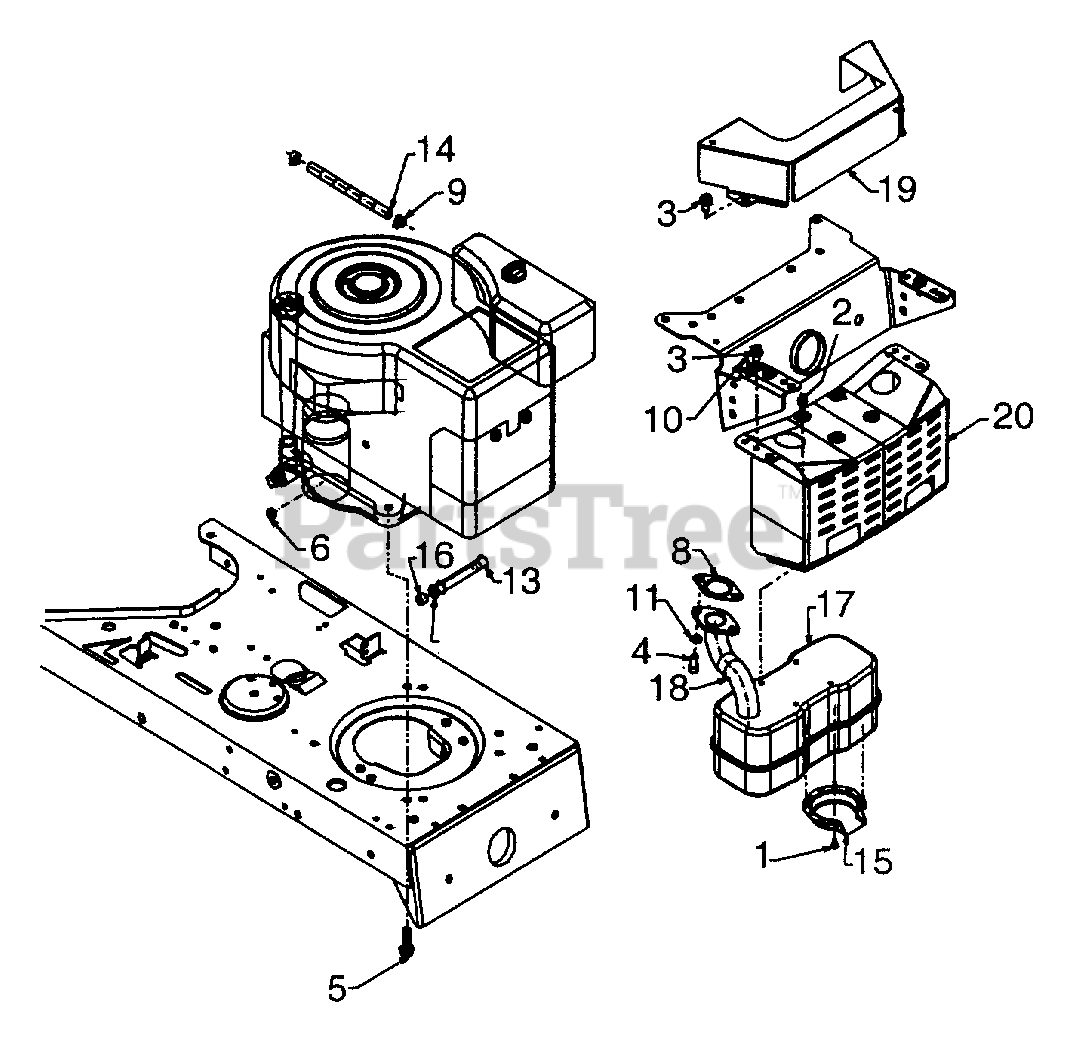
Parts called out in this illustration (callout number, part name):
1	Hex Bolt #8-32 x .38" Lg.
2	Hex Wash. Hd. TT Scr. 1/4-20 x .5" Lg.
3	Hex Wash. Hd. TT Scr. 5/16-18 x .62"
4	Socket Hd. Bolt 5/16-18 x .62" Lg.
5	Hex Wash. Hd. TT Scr. 3/8-16 x 1.25"
6	Hex Sems Nut 1/4-20 Thd.
8	Exhaust Gasket
9	Hose Clamp
10	Clamp
11	Lock Washer 5/16" I.D.
13	Pipe 3/8 NPT x 3.8" Lg. (16/17 HP)
14	Fuel Line
15	Muffler Deflector
16	Hex Pipe Plug (16/17 HP)
17	Muffler
18	Exhaust Pipe (16/17 HP)
